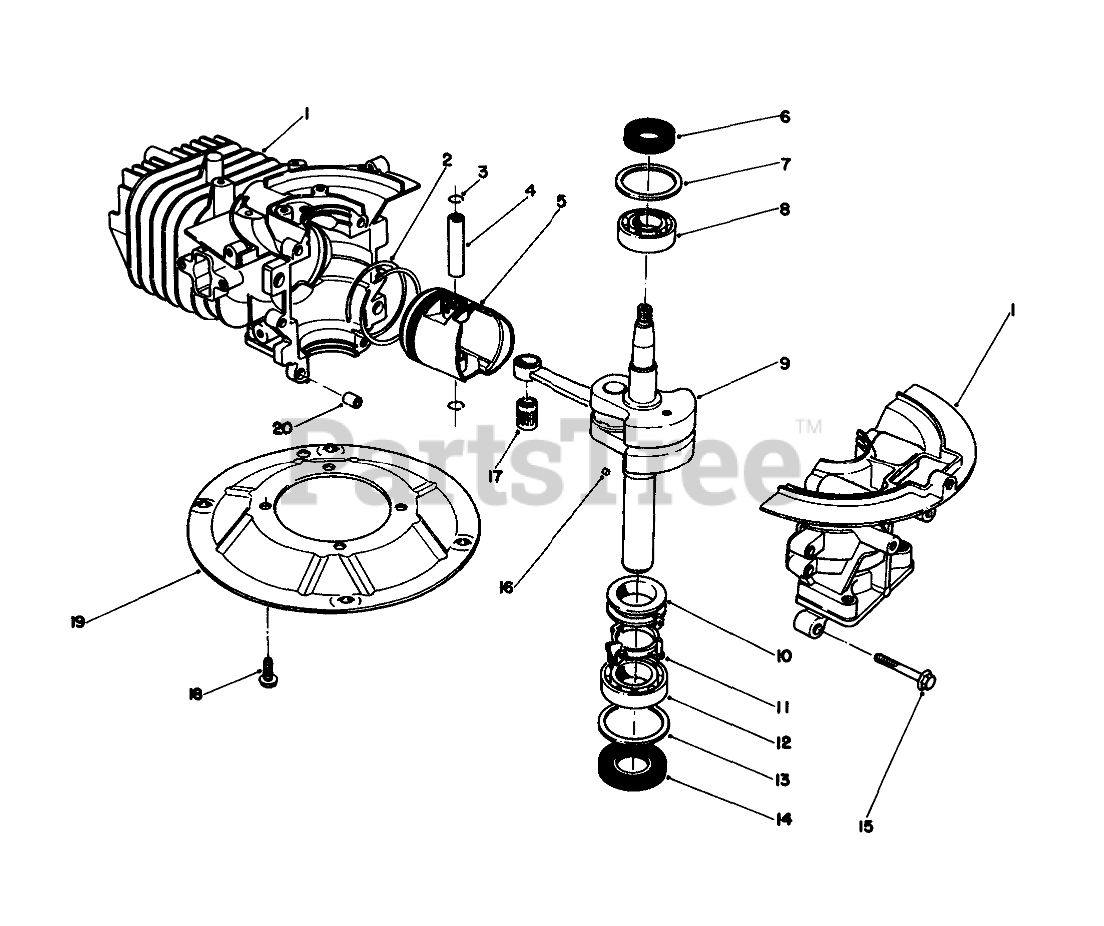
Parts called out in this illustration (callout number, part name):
1	CRANKCASE
2	RING SET
4	PIN-PISTON
5	PISTON
6	OIL SEAL
7	WASHER-UPPER
8	BEARING-UPPER
9	CRANKSHAFT
10	SPACER
11	BRACKET
12	LOWER BRG
13	WASHER-LOWER
14	SEAL-OIL
17	BEARING
19	PLATE-MOUNTING
